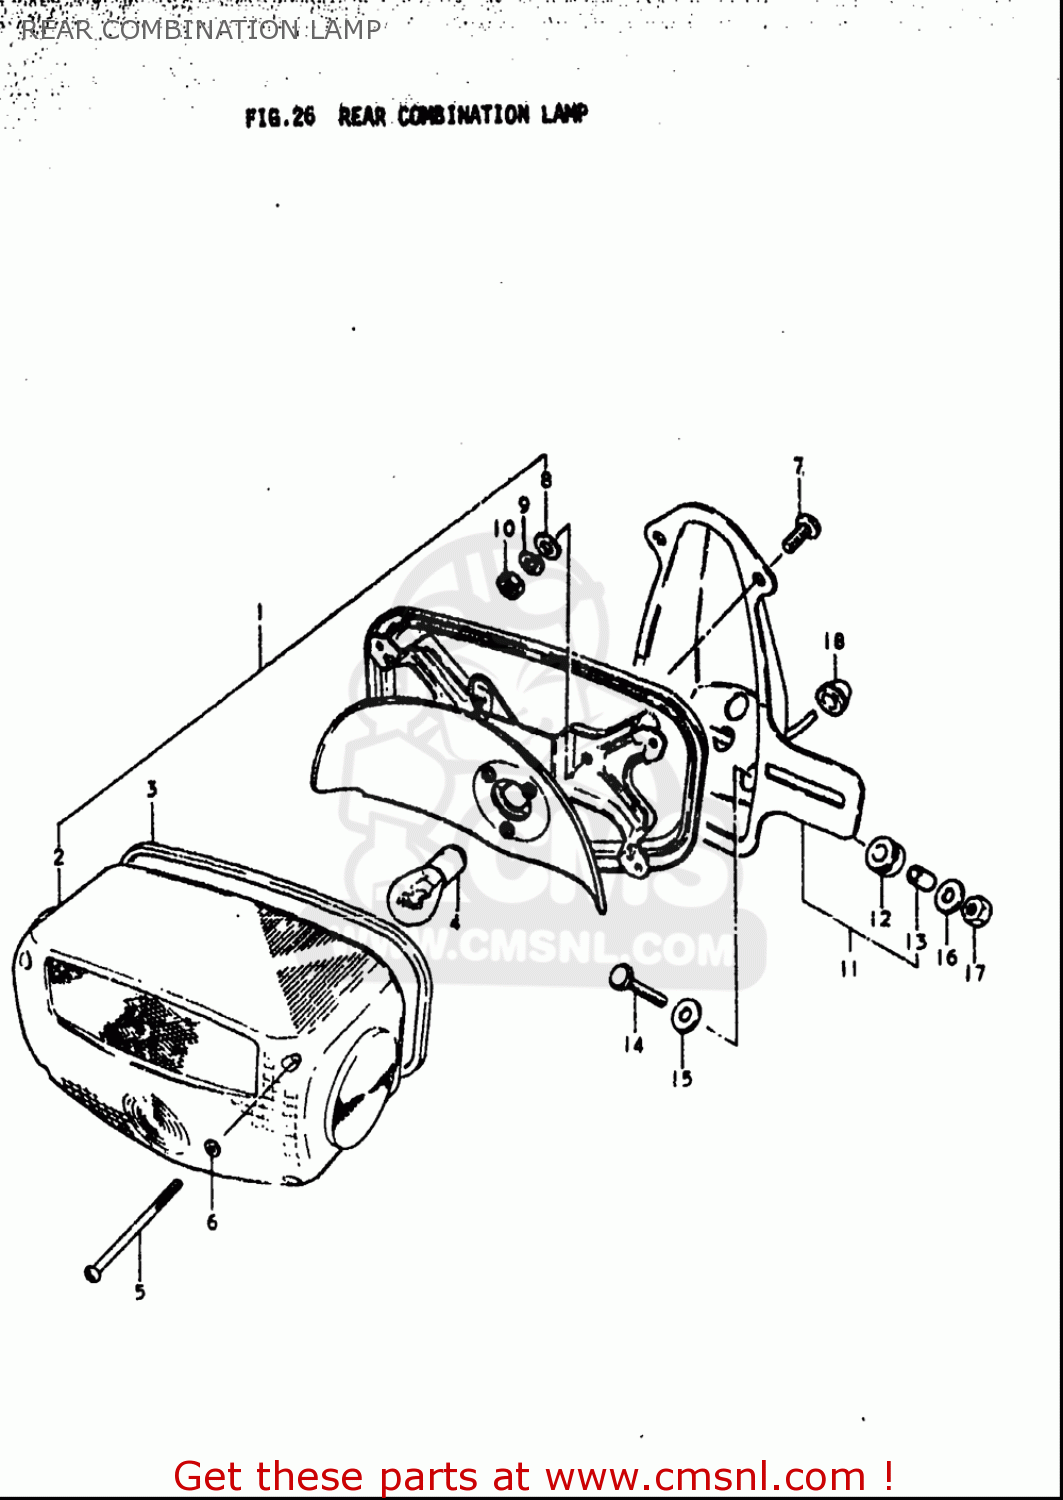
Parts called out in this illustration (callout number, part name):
1	LAMP UNIT,REAR COMBINATION
2	LENS
3	GASKET (NAS)
4	BULB(12V23W)
6	GASKET (NAS)
7	SCREW
8	WASHER
9	WASHER,LOCK
10	NUT
12	CUSHION
13	SPACER
14	BOLT
15	WASHER(6.5X20X1.2)
16	WASHER
17	NUT
18	GROMMET
